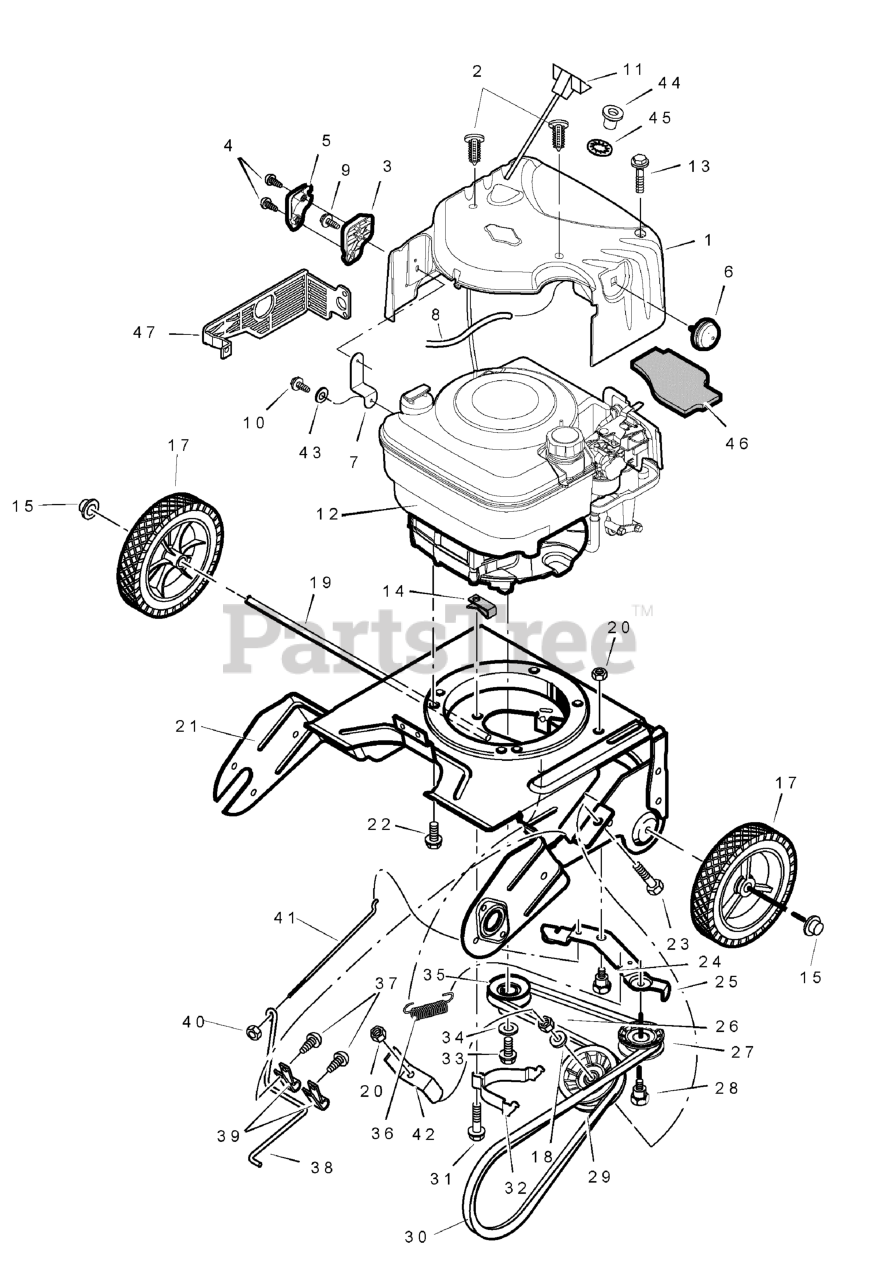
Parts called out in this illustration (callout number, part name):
1	Cover, Engine
2	Screw, #8x1.25
3	Base, Chute Rod
4	Screw, #10-14x.62
5	Cover, Chute
6	Primer-Carburetor
7	Bracket, Engine Chute
8	Hose, Primer 5 3/4 Inches
11	Grip, Standard Recoil
12	Engine
13	Bolt, #10-24x1.75
14	Retainer
15	Nut, Push Cap
17	Tire & Rim
18	WASHER, Flat, 13/32
20	Nut, 3/8-16
21	Frame, Motor Box
22	Bolt, 3/8-16x1.00
23	Screw
24	Bolt, Shoulder .375-16x.640
25	Bracket, Idler Arm
26	Nut
27	Pulley, Idler V-Belt
28	Bolt, Shoulder
29	Pulley, Flat Idler
31	Screw, 1/4-14x1.25
32	Guide, Belt
33	Screw, 5/16-24 x 1.00
34	Washer, Sptlk .31x.58
35	Pulley, 2.50 4L .75ID
36	Spring, Extension
37	Screw, 1/4-20
38	Arm, Brake
40	Nut, 10-24
41	Rod, Adjustment
42	Guide, Belt/Brace
43	Washer, Lock
44	Guide, Rope
46	Seal, Foam
47	Guard, Muffler
